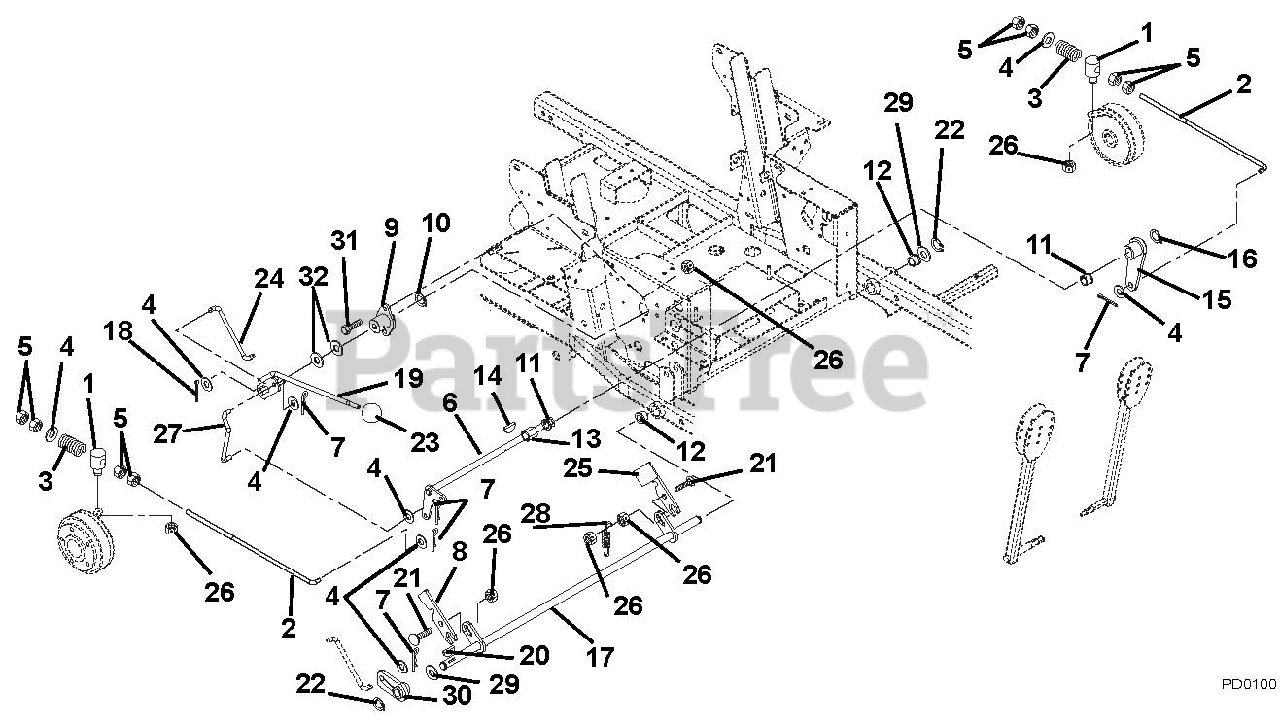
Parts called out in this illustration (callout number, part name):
1	Pivot, Brake Rod
2	Rod, Brake .38 x 19.00
3	Spring, Compression .142 x .710 x 1.75
4	Washer, Flat Steel .406 x .812 x .065
5	Nut, Hex .38-16
6	Shaft, Brake Cross
7	Pin, Hair
8	Slide, Interlocking Brake
9	Bushing, Flange
10	Ring, Retaining External .625 x .05
11	Bushing, Flange Nylon .762 x 1.00 x .58 x 1.48
12	Bushing, Flange .515 x .75 x .745 x 1.00
13	Bushing, Sleeve .75 x 1.00 x .75
14	Key, Woodruff .19 x .75 Hard #9
15	Arm, Brake Left Hand
16	Ring, Retaining External .625 x .050
17	Weldment, Mechanical Brake
18	Pin, Cotter External .09 x .75
19	Weldment, Brake Handle
20	Key, Woodruff .13 x .63
21	Bolt, Round Head Square Neck .31-18 x 1.25 Grade 5
22	Ring, Retaining External .50 x .05
23	Grip, Handle
24	Linkage, Brake Actuating
25	Interlock, Safety Switch
26	Nut, Locking, Top Flange .31-18
27	Linkage, Brake Actuating
28	Spring, Tension .063 x .44 x 1.56
29	Washer, Flat Steel .505 x 1.00 x .062
30	Weldment, Parking Brake Hub
31	Bolt, Hex .31-18 x .75 Grade 5
32	Washer, Flat Steel .630 x 1.250 x .062
